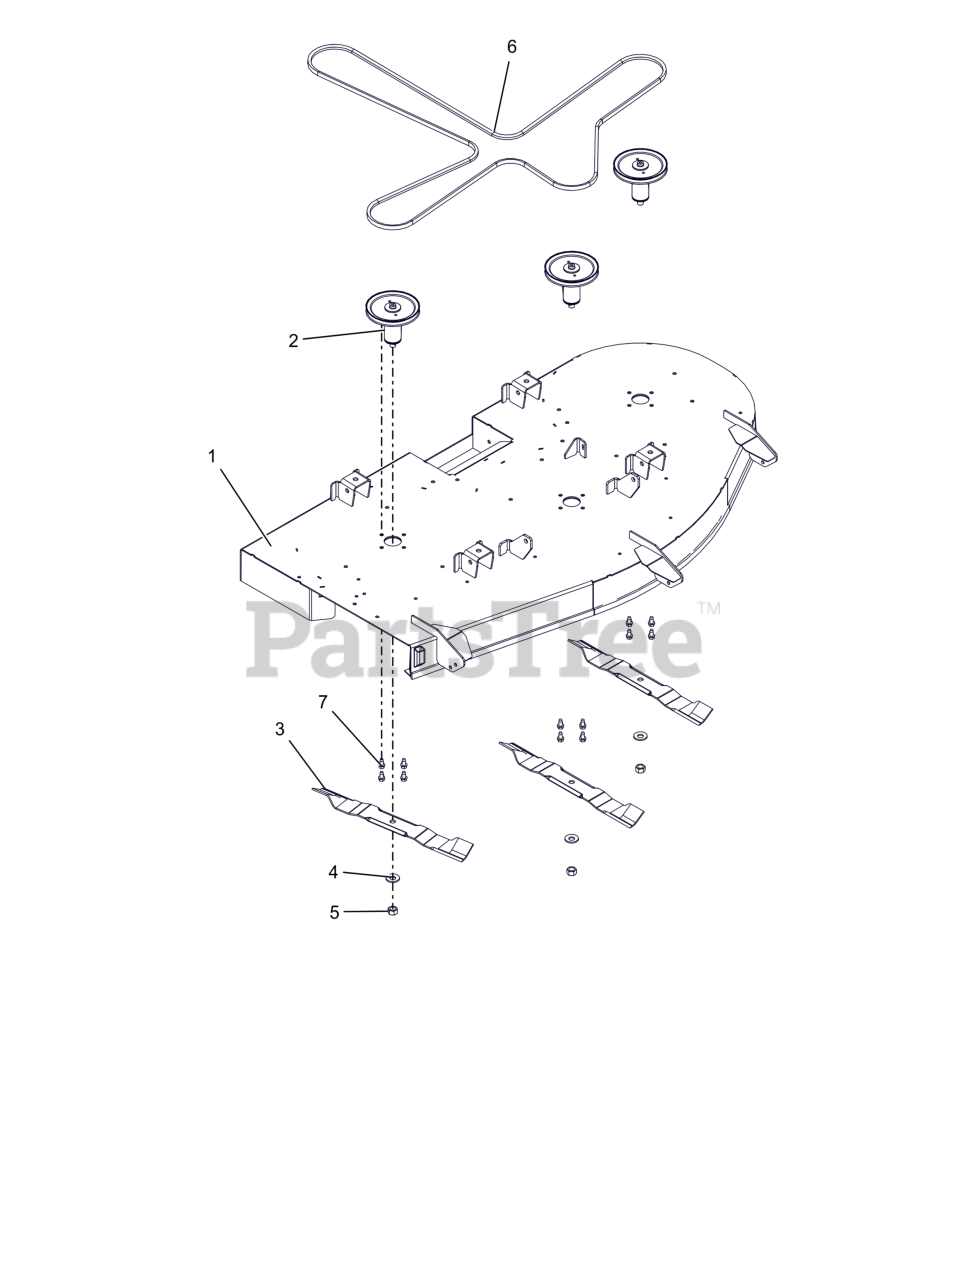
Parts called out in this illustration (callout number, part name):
1	KIT, 60" GRAVELY DECK W/DECALS
2	KIT, DECK SPINDLE ASM-60
3	BLADE, 21" 35 DEG
4	WSHR-BLVL .669X1.535X.138
5	NUT-STD .625-18 ZCC
6	BELT, HA
7	SCR,TAP .375-16X.75 HWH TR ZCC
